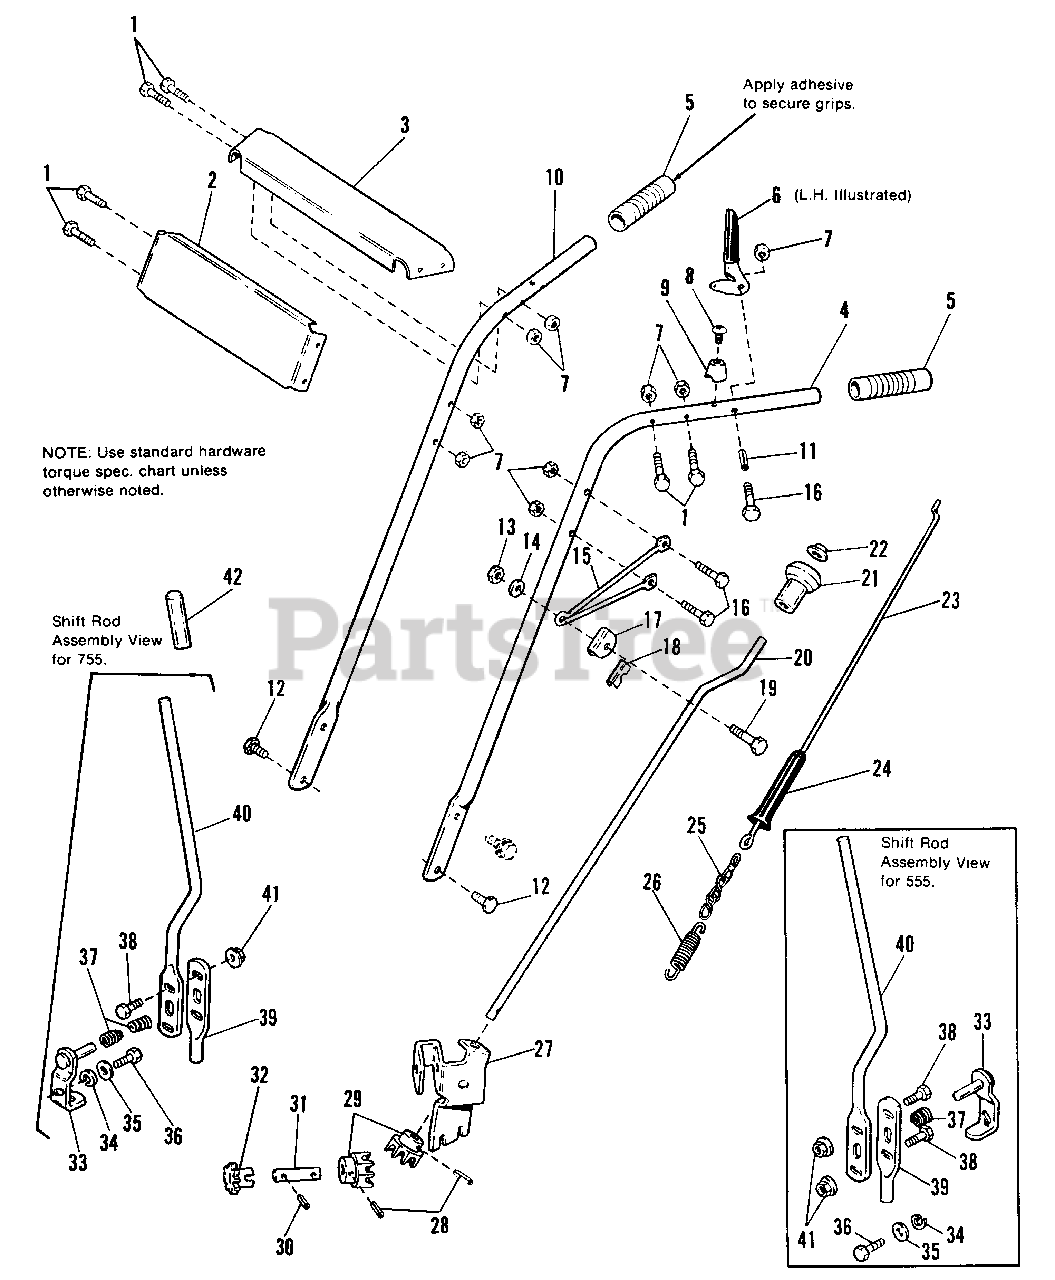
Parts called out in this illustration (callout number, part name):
1	CAPSCREW, Hex, 1/4-20 x 1-1/4
2	HANDLE PANEL, Lower
3	HANDLE PANEL, Upper
4	HANDLE, Tube, L.H.-Chrome Finish (Early Models 5 HP)
4	HANDLE, Tube, L.H.-Black Finish (Later Models 5 HP & All 7 HP)
5	GRIP, Handle
6	CLUTCH LEVER ASSY., L.H.
7	NUT, Centerlock, 1/4-20
8	SCREW, Thd. Cutting Pan Hd. #10-24
10	HANDLE, Tube, R.H.-Chrome Finish (Early Models 5 HP)
12	SCREW, Special, 5/16-18 x 3/4
13	NUT, Hex, Centerlock, 5/16-18
14	WASHER, 5/16
15	BRACKET, Control Rod
16	CAPSCREW, Hex, 1/4-20 x 1-1/2
17	GUIDE, Adj. Rod
18	LINER, Rod Guide
19	CAPSCREW, Hex, 5/16-18 x 1-1/2
20	ROD, Chute Control
21	KNOB, Spinner
22	PALNUT
23	ROD, Clutch
24	SLEEVE, Vinyl
27	SUPPORT, Gear
28	PIN, Roll, 1/8 x 3/4
29	GEAR, Universal
30	PIN, Roll, 5/32 x 1
31	ROD, Chute, Lower
32	SPROCKET, Chute
33	ARM, Shift Assy.-5 HP Only
34	LOCKWASHER, 1/4
35	WASHER, 1/4
36	CAPSCREW, Hex, 1/4-20 x 5/8
37	SPRING (Qty. 2 on 7 HP)
38	CAPSCREW, Hex, 1/4-20 x 3/4
39	SHIFT ROD, Lower
40	SHIFT ROD, Upper-5 HP Only
41	NUT, Hex, Whizlock, 1/4-20
